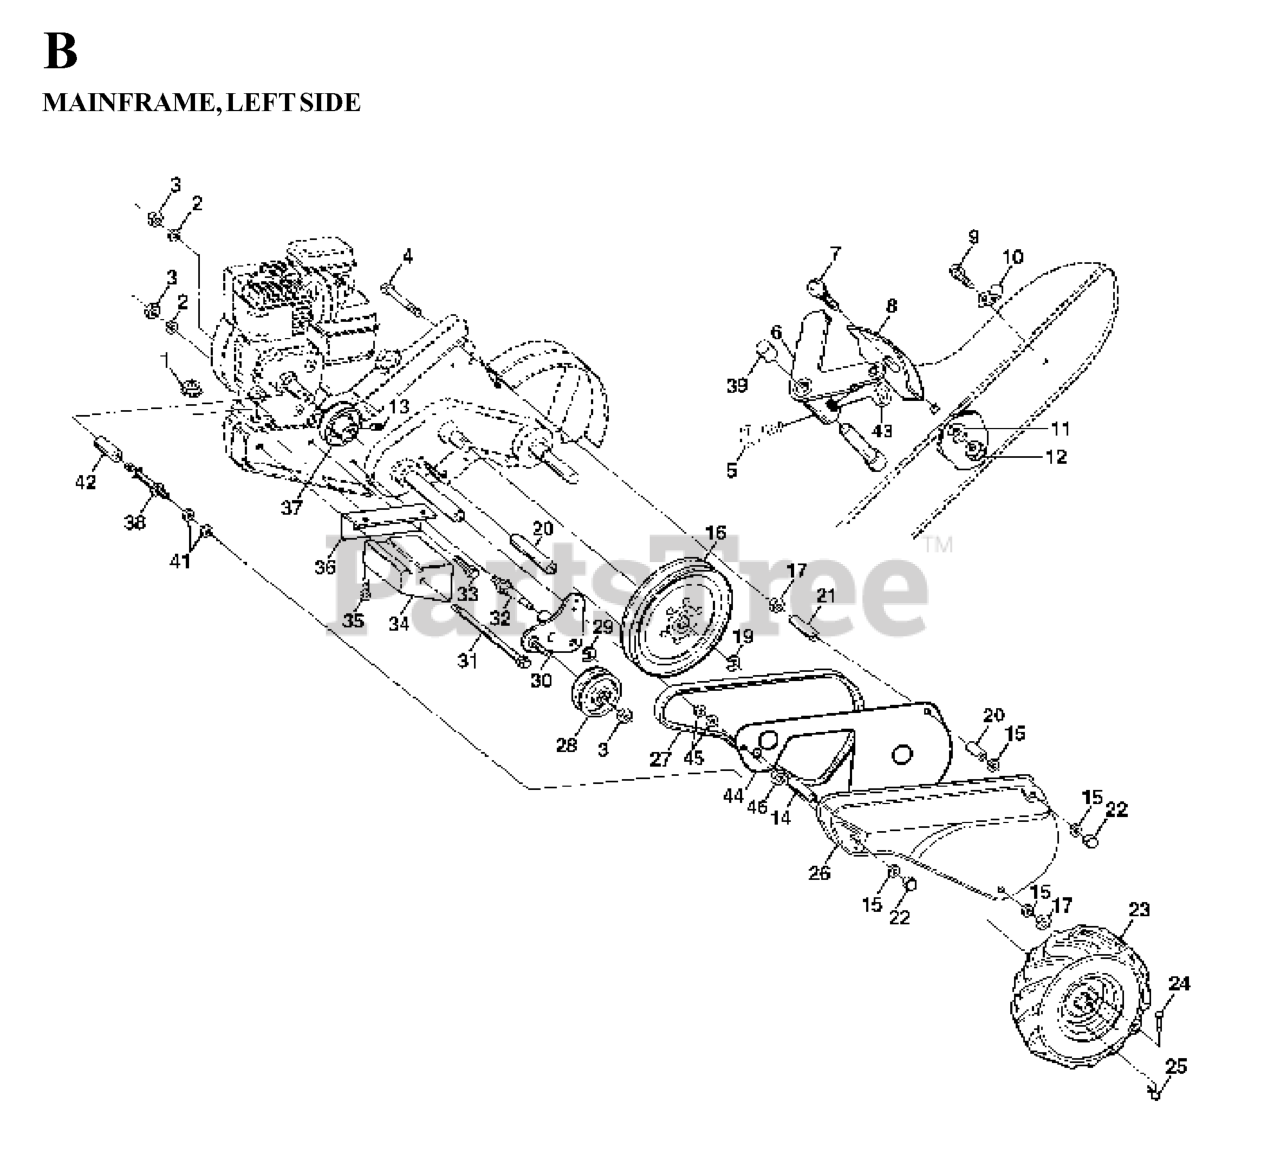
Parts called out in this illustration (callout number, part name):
1	NUT
2	WASHER, LOCK 3/8
3	NUT.HEX.3/8-16UNC
4	Bolt, Hex 5/16-18 x 4-1/4
5	SCREW, SHIFT LEVER
6	LEVER ASM CRT
8	PANEL.INDICATOR.SHIFT.BLACK
9	TAPPING SCREW
10	CONDUIT.CLIP.PLATED
11	LOCKWASHER
12	NUT
14	SPACER-SPLIT.327 X .42
15	WASHER
16	SHEAVE, TRANSMISSION
19	RETAINING RING LT
23	TIRE.16X4-8.CHEVRON.TILLER
24	RIVET,DRILLED
25	RETAINER M
26	BELT GUARD
27	V-BELT
28	PULLEY-IDLER TI
30	BRACKET ASSY TI
31	BOLT.FIN.HEX.3/8-16UNC
32	SHIFT ARM CRT
33	BOLT
34	COUNTERWEIGHT.LH.CRT
35	Bolt Fin Hex 5/16 - 18 Unc x 2 Gr. 2
36	BRACKET LH CRT
37	RP.ENGINE PULLEY
38	BELT GUARD STUD
39	CAP.PLUNGER.BLACK
46	LOCKNUT.NYLOC.1/4-20
532124366	RIM
532124718	VALVE STEM LT
